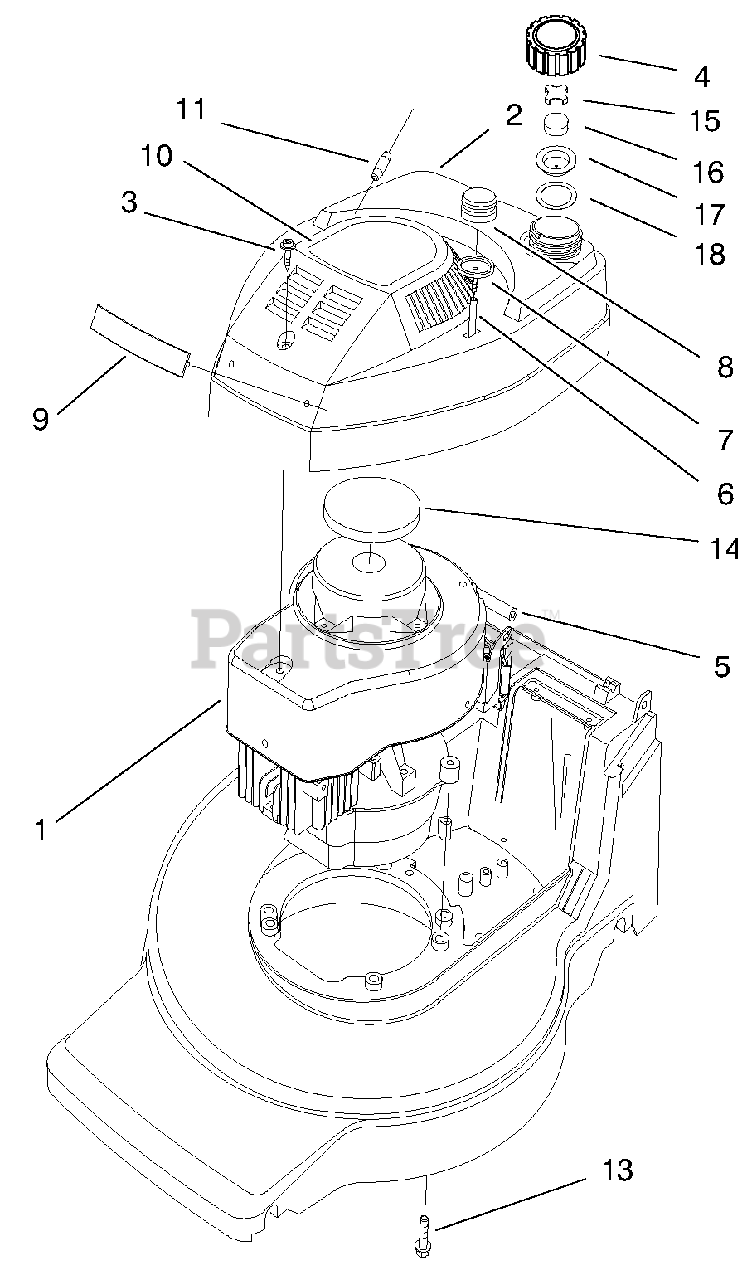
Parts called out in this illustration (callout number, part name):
1	Engine Assembly
2	Shroud & Tank Assembly
4	Fuel Cap Assembly
5	Gas Line
6	Hose Primer
7	Body-Primer
8	Bulb-Primer
9	Applique-Shroud
10	Decal-Shroud Top
11	Rope-Stop
14	Disc-Foam
16	Baffle-Foam
